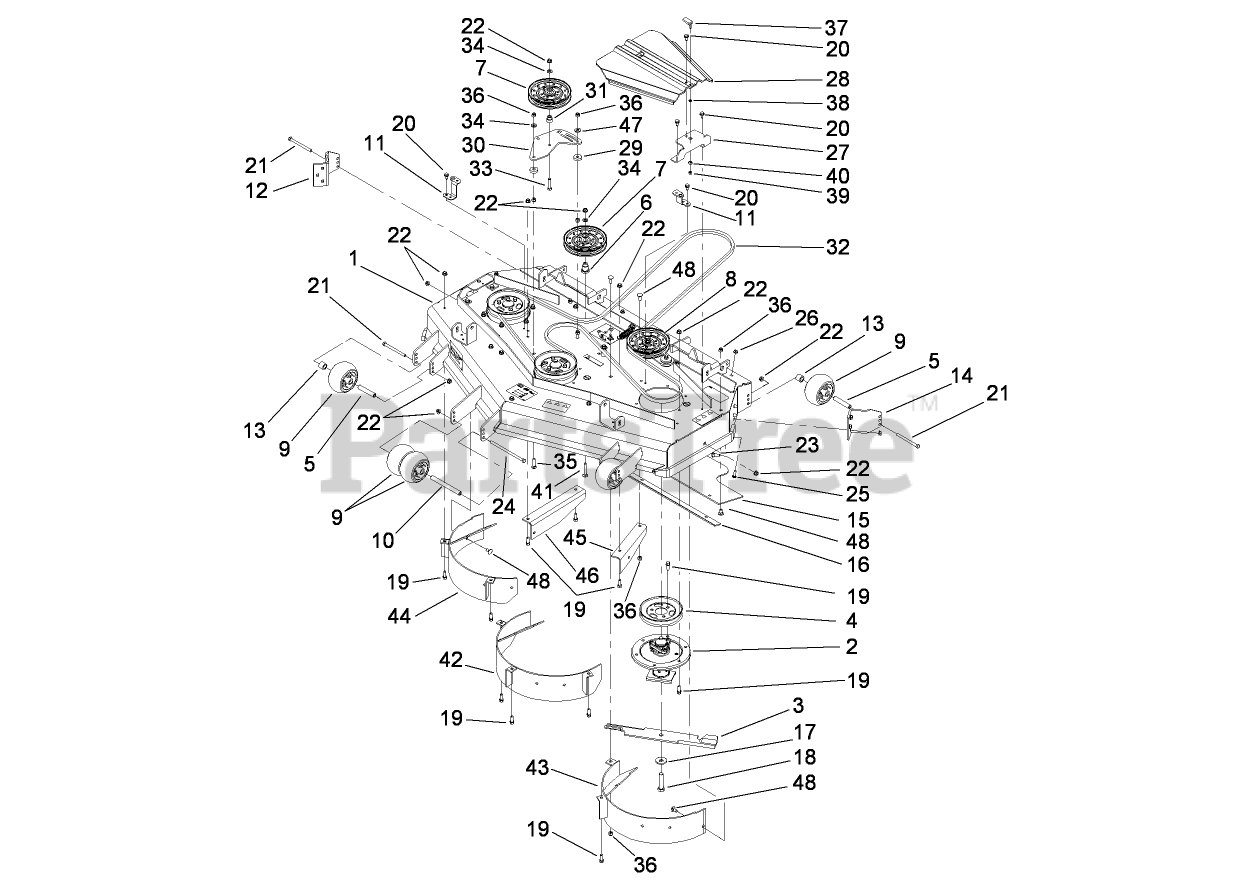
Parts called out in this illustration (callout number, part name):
1	DECK DECAL ASM
2	SPINDLE ASM
3	BLADE-18IN, HI FLOW
4	Pulley
5	TUBE-SPANNER
6	MOUNT-PULLEY
7	Idler-Flat
8	SPRING IDLER ASM
9	ROLLER-SCALP, ANTI
10	SPACER-WHEEL
11	BRACKET-COVER, TALL
12	MOUNT-ANTI SCALP, RH
13	TUBE-SPACER
14	MOUNT-ANTI SCALP, LH
15	DEFLECTOR-RUBBER
16	SKID-SKIRT
17	Washer-Blade Bolt, Heavy
18	Screw-Cap
19	SCREW-HWH
20	SCREW-HWHTF
21	SCREW-HH
22	NUT-HHF, WHIZ
23	BOLT-CARR
24	SCREW-HH
25	SCREW-CARR
26	NUT-HF
27	BRACKET-BELT COVER
28	COVER-BELT
29	Spacer
30	PLATE-IDLER
31	BUSHING-IDLER
32	BELT-V
33	SCREW-HH
34	WASHER-FLAT
35	SCREW-CARR
36	NUT-LOCK, NI
37	HANDLE-LATCH, SWELL
38	WASHER
39	NUT-LOCK, HH
40	BUSHING-LATCH, SWELL
41	SCREW-CARR
42	BAFFLE-CENTER
43	BAFFLE-LH
44	BAFFLE-RH
45	BAFFLE-TRAILING
46	BAFFLE-TRAILING
47	WASHER-BELLEVILLE
48	SCREW-CARR
